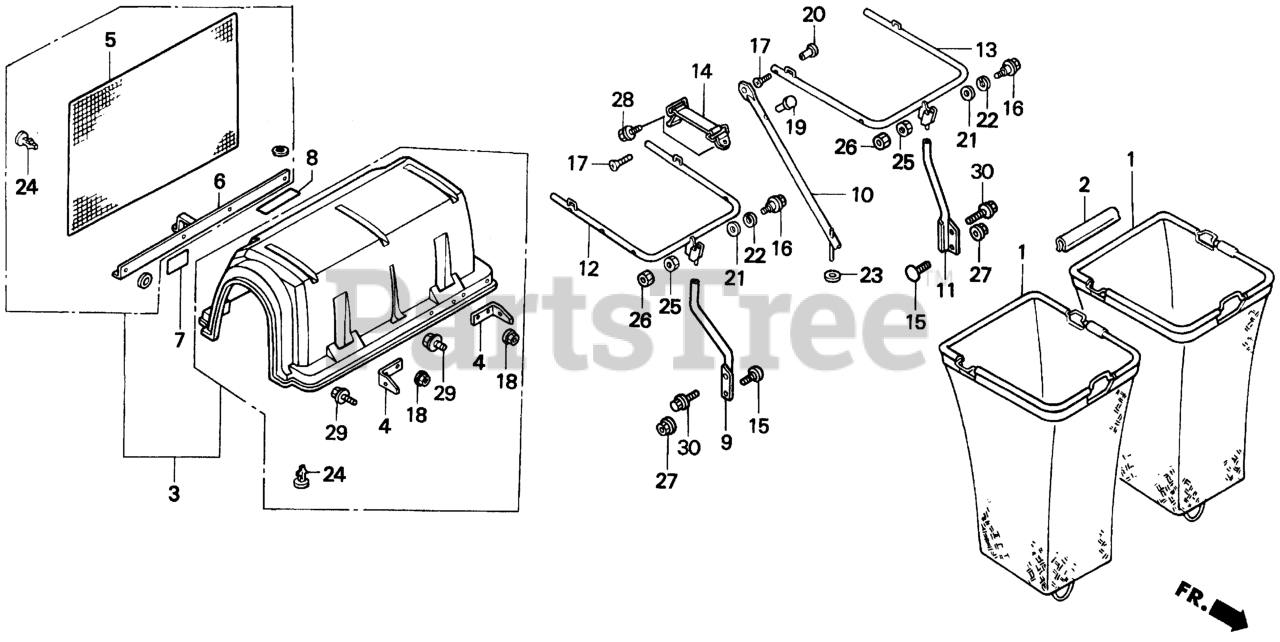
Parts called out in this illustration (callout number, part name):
1	BAG ASSY., GRASS
1	BAG ASSY., GRASS (ENGLISH)
1	BAG, GRASS
2	CLIP, GRASS BAG TUBE (NOT AVAILABLE)
3	HOPPER ASSY., TOP
4	HINGE, HOPPER TOP
6	STIFFENER, RR. (N/A: SEE ASSEMBLY)
7	LABEL, HOPPER TOP (A)
8	LABEL, HOPPER TOP ROOF (A)
9	POST, R. SUPPORT
10	BRACE, SUPPORT (US)
11	POST, L. SUPPORT
12	STAY, R. SUPPORT (NOT AVAILABLE)
13	STAY, L. SUPPORT
14	BAND ASSY., HOPPER TOP
15	BOLT, SPECIAL (8X20)
16	BOLT, HINGE (10MM)
17	SCREW, FLAT (8X45)
18	NUT, FLANGE (6MM)
19	NUT, PIPE (6MM)
20	NUT, PIPE (8MM)
21	WASHER, THRUST (14MM)
22	WASHER, SPRING (14MM)
23	WASHER (3/8")
24	CLIP, SCREEN
25	NUT, HEX. (10MM) (NOT AVAILABLE)
26	NUT, HEX. (10MM) (SOURCE: VINTAGE PARTS INC.)
27	NUT, FLANGE (8MM)
28	BOLT, FLANGE (6X16) Use from Engine SN 2056820.
29	BOLT, FLANGE (6X18)
30	BOLT, FLANGE (8X20)
